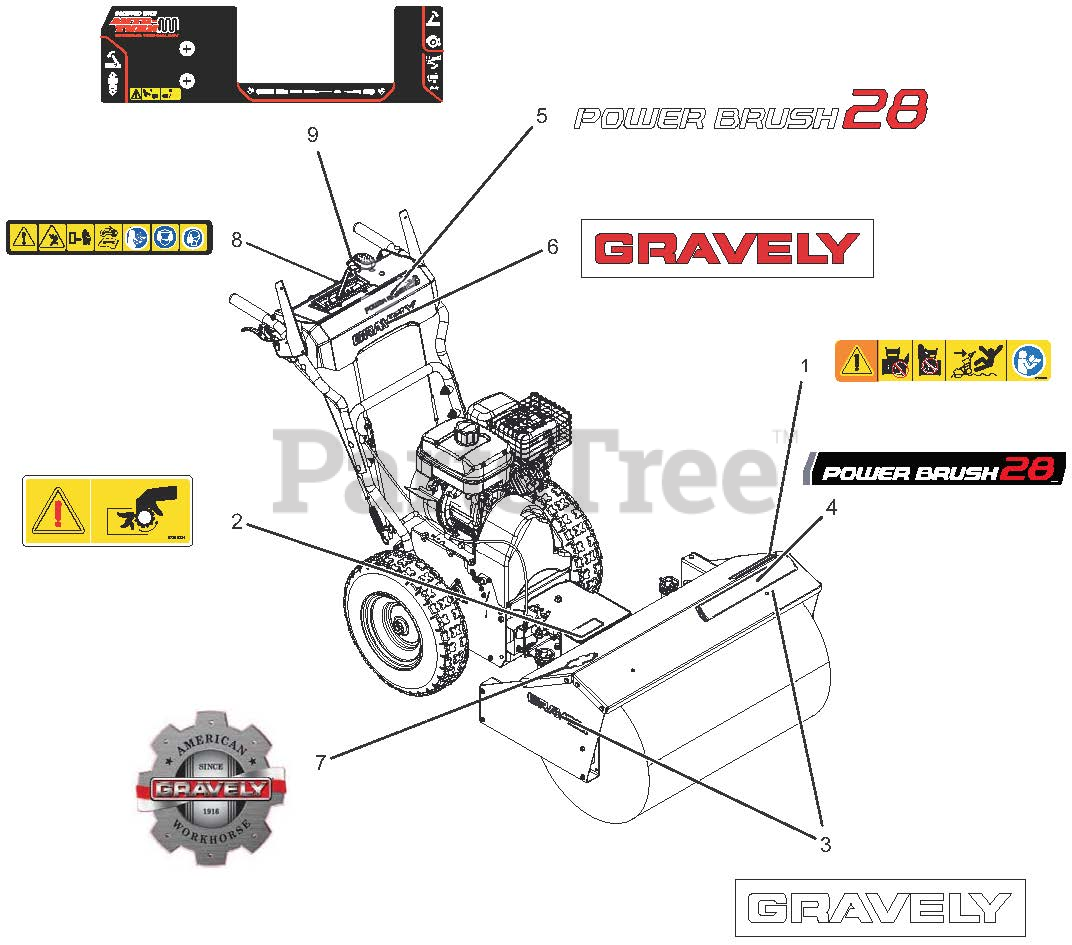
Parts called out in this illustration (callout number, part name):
1	DECAL, DANGER -POWER BRUSH-CE
2	DECAL, PTO WARNING
3	DECAL, 9.5" GRAVELY LOGO
4	DECAL,POWER BRUSH 28,GRAVELY
5	DECAL,POWER BRUSH 28,GRAVELY
6	DECAL,GRAVELY,RED,9.5"
7	DECAL, GRAVELY HERITAGE-LARGE
8	DECAL, SAFETY, DASH, BRUSH
9	DECAL, CONTROL-SMALL BRUSH
